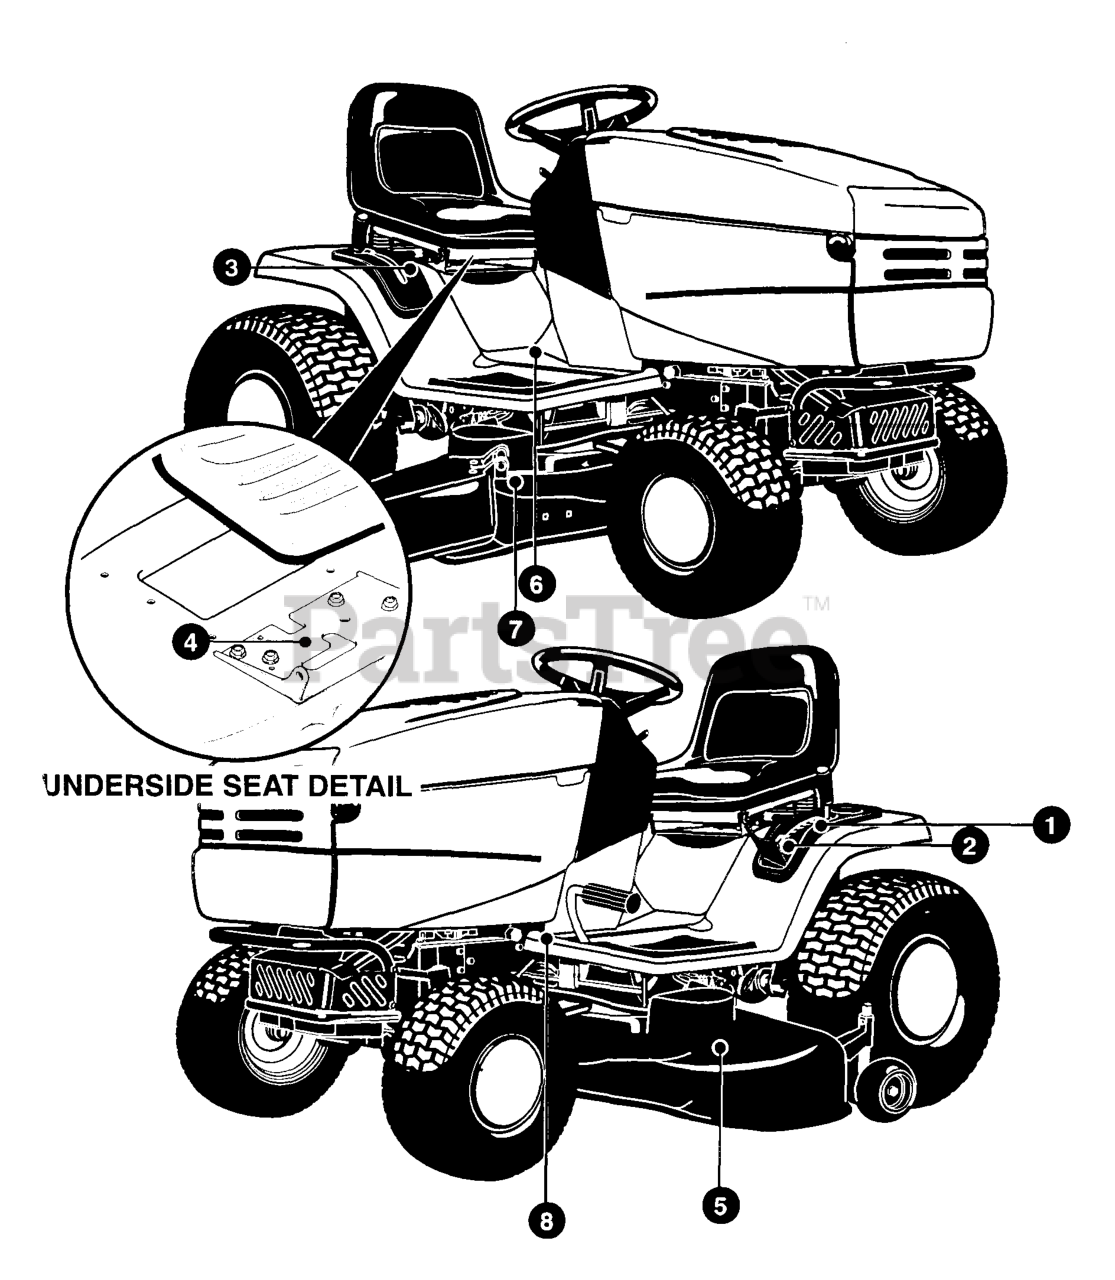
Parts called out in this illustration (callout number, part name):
1	DECAL, HEIGHT ADJUST 1-6
2	DECAL, DECK LEVEL
3	DECAL, CRUISE CONTROL
4	DECAL, HYDRO REL. VALVE
5	DECAL, NO STEP DOM WH/CLEAR
6	DECAL, INST CONS.
7	DECAL, DOM CUT FINGER/OPEI98
8	DECAL, CLUTCH/BRAKE TOE
